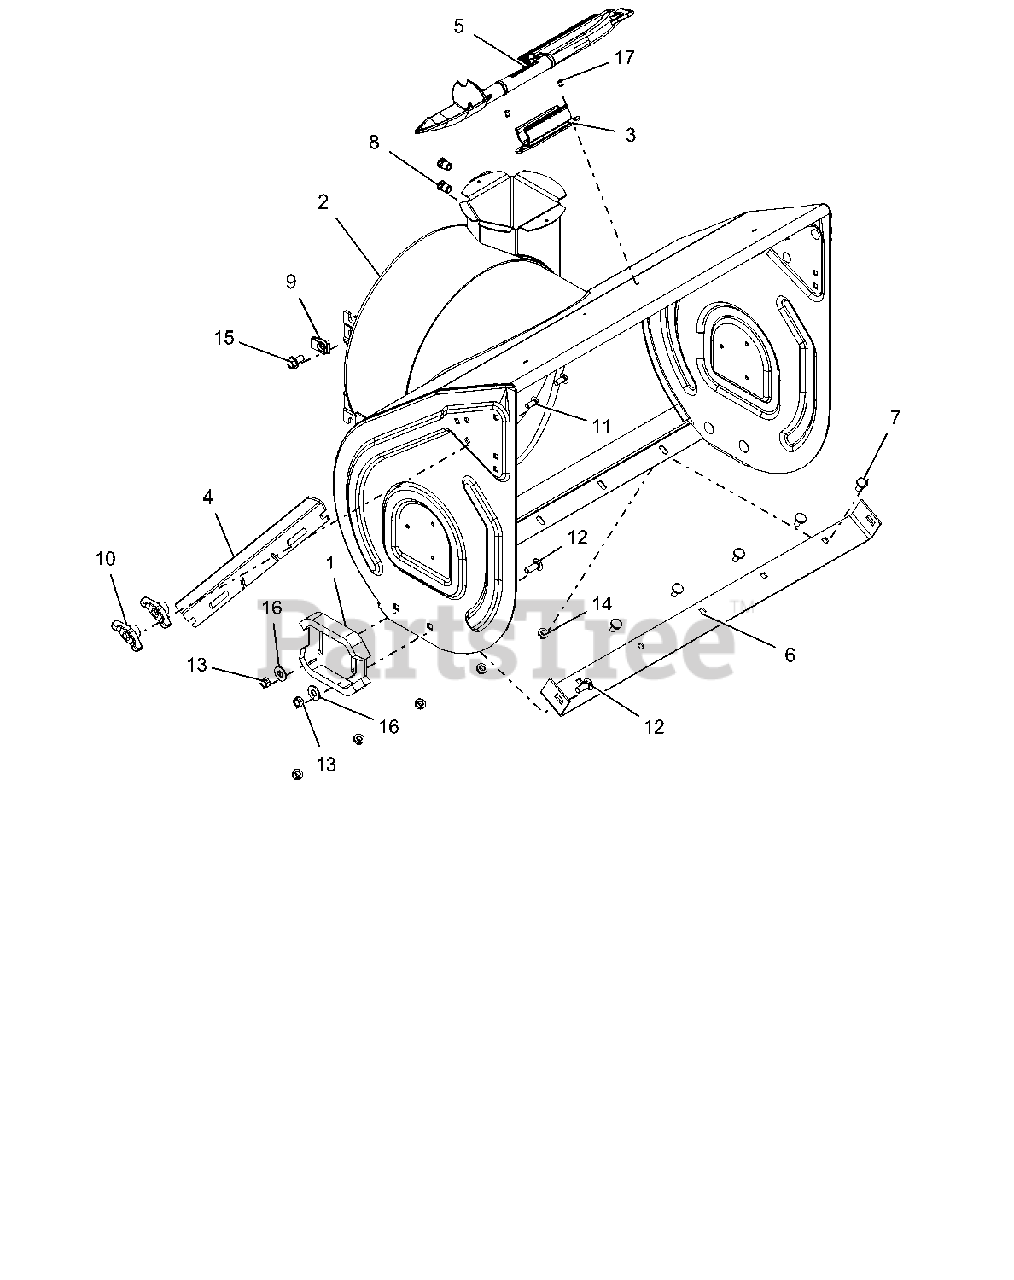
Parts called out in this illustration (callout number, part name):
1	RUNNER, SKID SHOE
2	BLOWER HOUSING W/DECAL 28"
3	MOUNT, SNOW CLEAN OUT
4	CUTTER, DRIFT
5	DEVICE, SNOW CLEAN OUT W/BRUSH
6	BLADE, SCRAPER-28"
7	BOLT, MODIFIED HEAD CARRIAGE
8	NUT, THREADED INSERT .38-16
9	NUT-RTNR .375-16X.37
10	KNOB,WING .31-18 UNC NYL/TALC
11	@BLT-RHDSSQNK .31-18X.75 G5YZ
12	@BLT-RDHDSHSQNK.38-16X1.0 G5YZ
13	@NUT-LK-CTR .38-16 YWZC
14	@NUT-LK-TOP-FLG .31-18 YWZC
15	BLT-SERHFWH .38-16X.75 YWZC
16	@WSHR-FL-STL.438X1.00X.083 YWZ
17	RVT-POP .187 YZ
